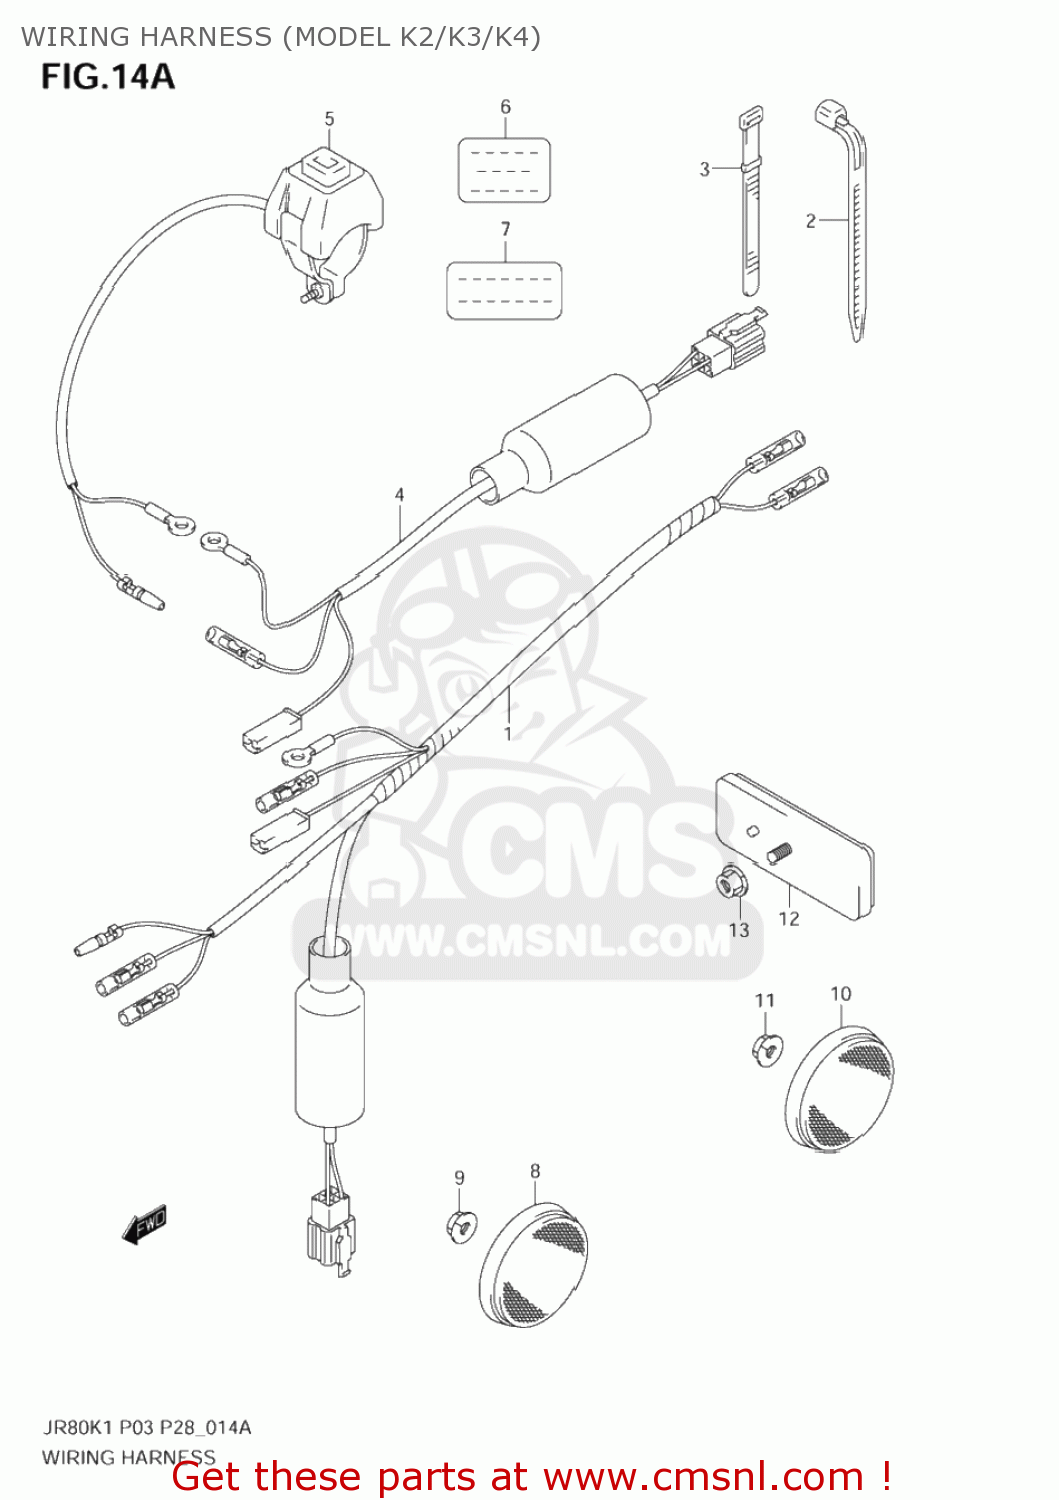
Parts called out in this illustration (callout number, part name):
1	HARNESS,WIRING
2	CLAMP(L:125)
3	CLAMP(L:120)
4	WIRE,MAGNETO LEAD
5	SWITCH ASSY,ENGINE STOP
6	LABEL,ENGINE STEP SWITCH
7	LABEL,ENGINE STEP SWITCH
8	REFLEX REFLECTOR,FR
9	NUT
10	REFLEX REFLECTOR,RR
11	NUT
12	REFLECTOR ASSEMBLY,REAR
13	NUT
